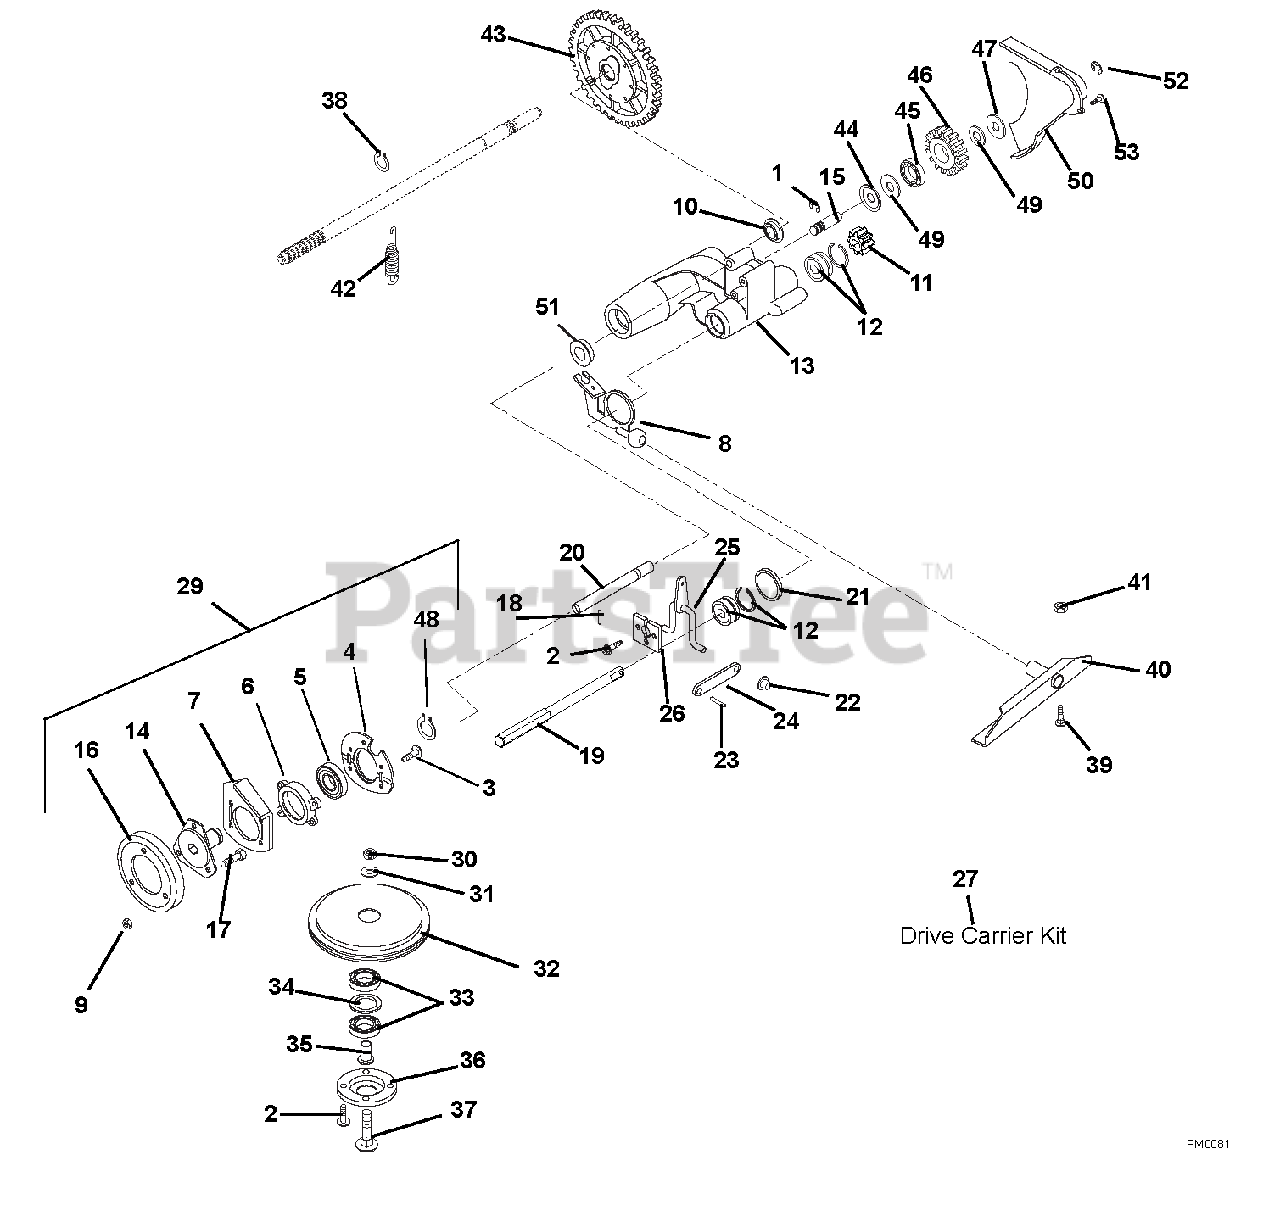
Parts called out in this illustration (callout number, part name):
1	RG-RTNG-EXT .438X.035
2	@SCR-TAP 12-24X.50 HWH TR YWZC
3	SCR-TAP 5HX-0.8X16MM H-FL-YWZC
4	BEARING RETAINER
5	BRG-BALL 1.0X2.0X.56 (1641)
6	BEARING RETAINER
7	PLATE, BEARING
8	ACTUATOR, WBLM DRIVE
9	@NUT-LK-CTR .25-20 YWZC
10	BRG-BALL .625X1.378X.44
11	PINION, D-SHAFT
13	DRIVE CARRIER
14	FRICTION WHEEL HUB
15	IDLER SHAFT
16	DISC, FRICTION - 730 MAT'L
17	@BLT-HEX .25-20X.50 GR5 YWZC
18	PIN-ROLL .188X.88
19	SHAFT, FRICTION DISK
20	ROD - GUIDE
21	WSHR-FL-STL 1.390X2.00X.020 PL
22	PUSH NUT, .25
23	PIN-ROLL .125X.50
24	SHIFT LINK
25	SHIFT ARM WELDMENT
26	RETAINER PLATE
27	KIT, LM DRIVE CARRIER
28	@WSHR-FL-STL.344X.688X.065YWZC
29	KIT, COM. DRIVE CONVERSION
30	@NUT-LK-CTR .31-18 YWZC
31	WSHR-FL-STL .328X.87X.179 YWZC
32	FRICTION SHEAVE
34	WSHR-FL-STL 1.062X1.344X.032PL
35	SPINDLE - BEARING
36	RETAINER - BEARING
37	@BLT-RDHDSQNK .31-18X1.75 G5YZ
38	RG-RTNG-EXT .579X.035
39	@BLT-RHDSSQNK .31-18X.62 G5YZ
40	PIVOT, CHANNEL WELDMENT
41	@NUT-LK-TOP-FLG .31-18 YWZC
42	SG-TENS .051X.60X2.25 WLD 7.0
43	DIFFERENTIAL ASSEMBLY
44	RETAINER
46	IDLER GEAR
47	WSHR-FL-STL.531X1.00X.063 YWZC
48	RG-RTNG-EXT 1.00X.042
49	WSHR-FL-STL .52X.827X.062 YWZC
50	COVER, GEAR
52	RG-RTNG-EXT .438X.035
53	@SCR-TAP 12-24X.50 HWH TR YWZC
